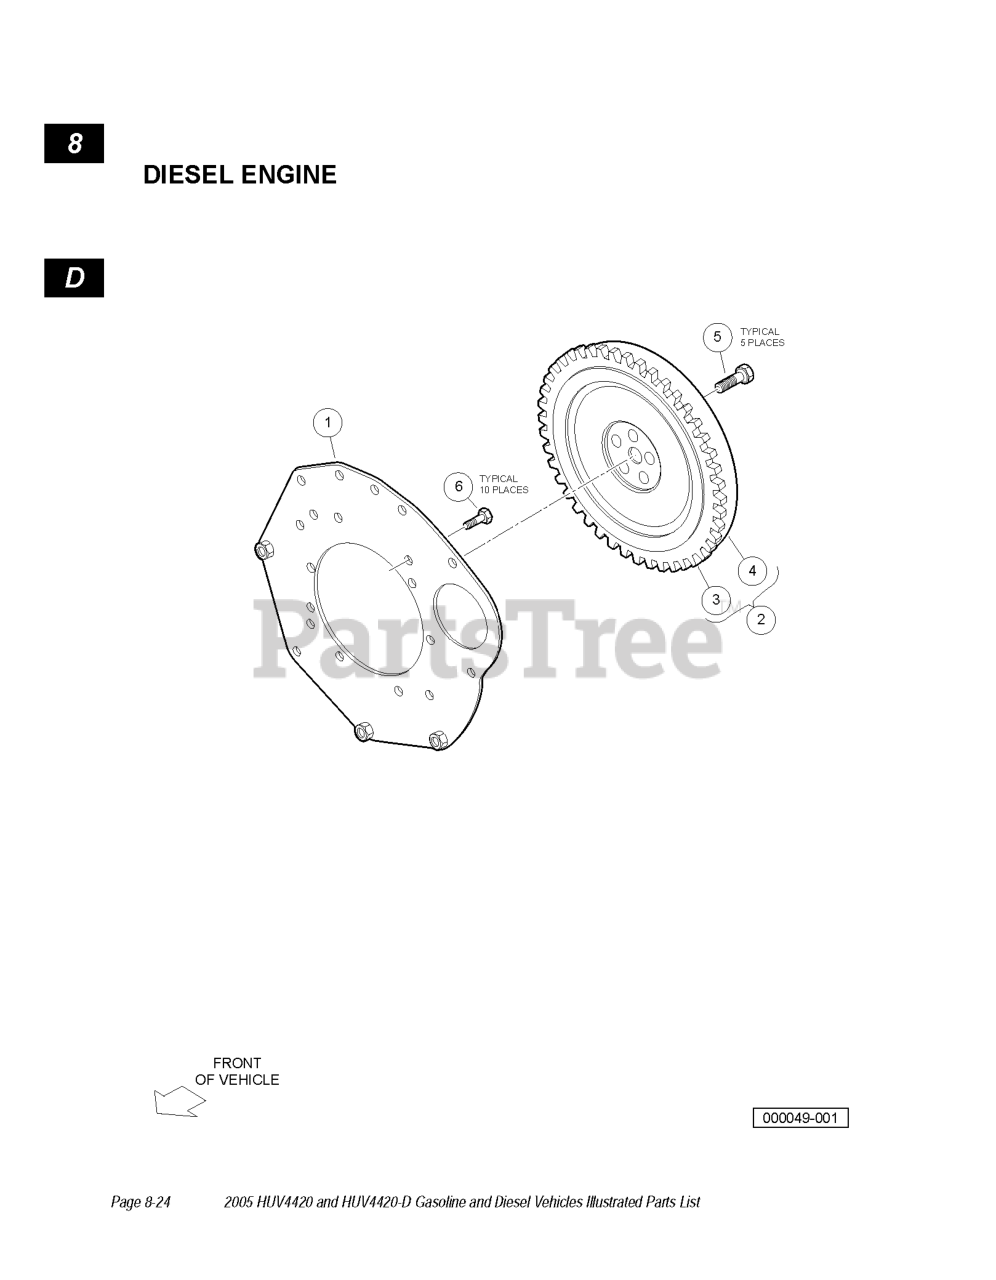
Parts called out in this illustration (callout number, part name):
1	PLATE, REAR END
2	COMP, FLYWHEEL
3	GEAR, RING, D722
5	BOLT, FLANGE, M10 X 1.5 X 25
6	BOLT, END PLATE
